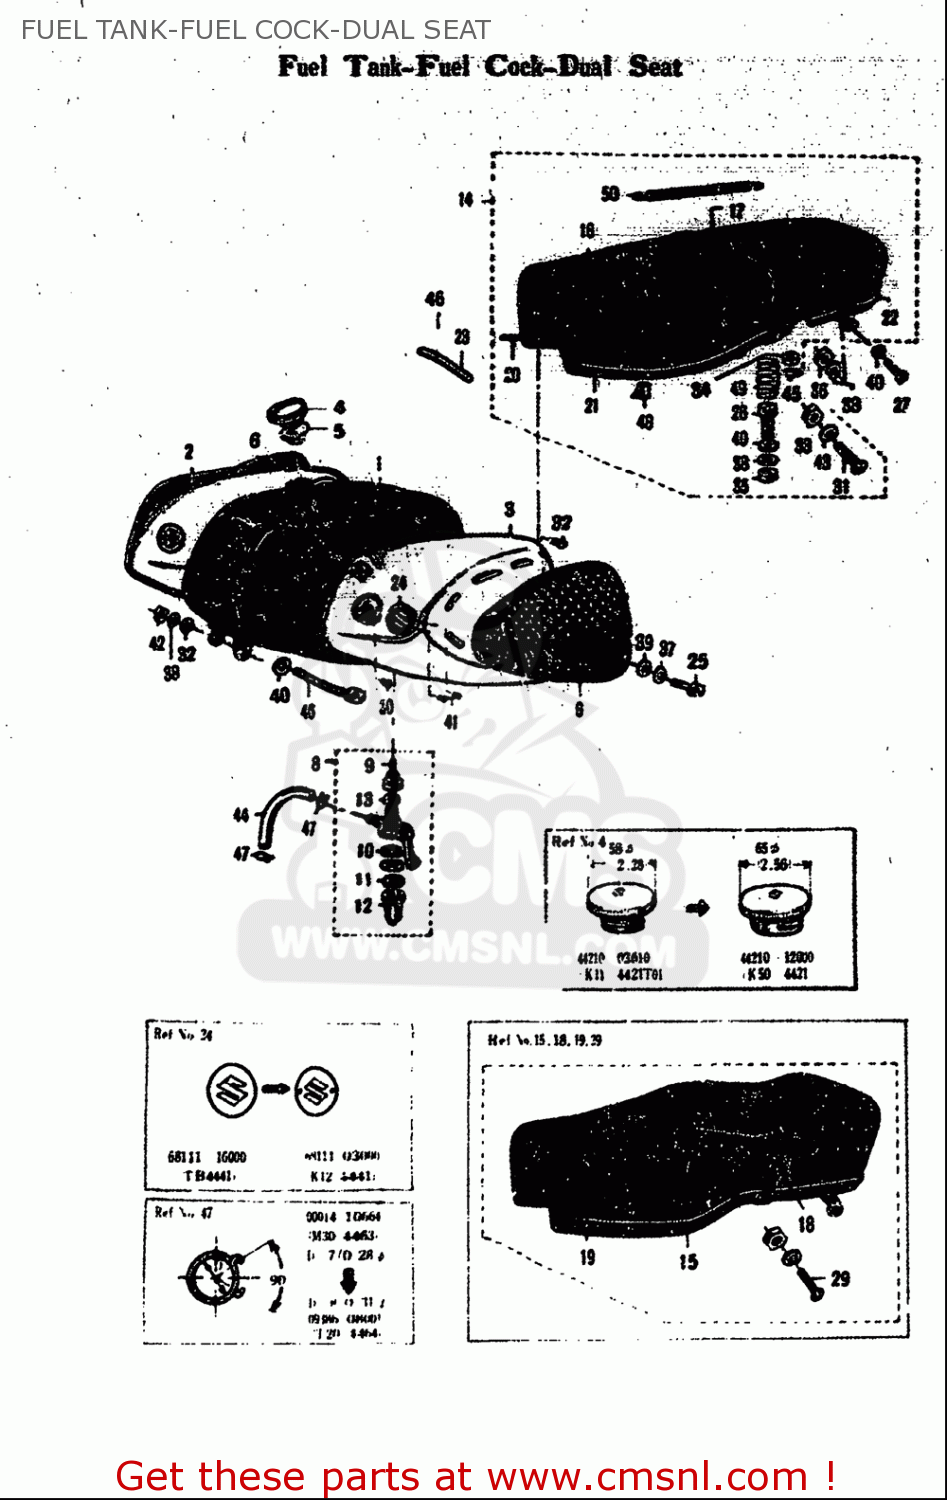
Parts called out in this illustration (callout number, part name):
4	CAP ASSY,FUEL TANK FILLER
8	COCK ASSY,FUEL
26	BOLT
29	SCREW
33	NUT
34	NUT
35	NUT
36	NUT
37	WASHER,LOCK
38	WASHER,LOCK
39	WASHER
40	WASHER
45	CLIP
46	CLIP
